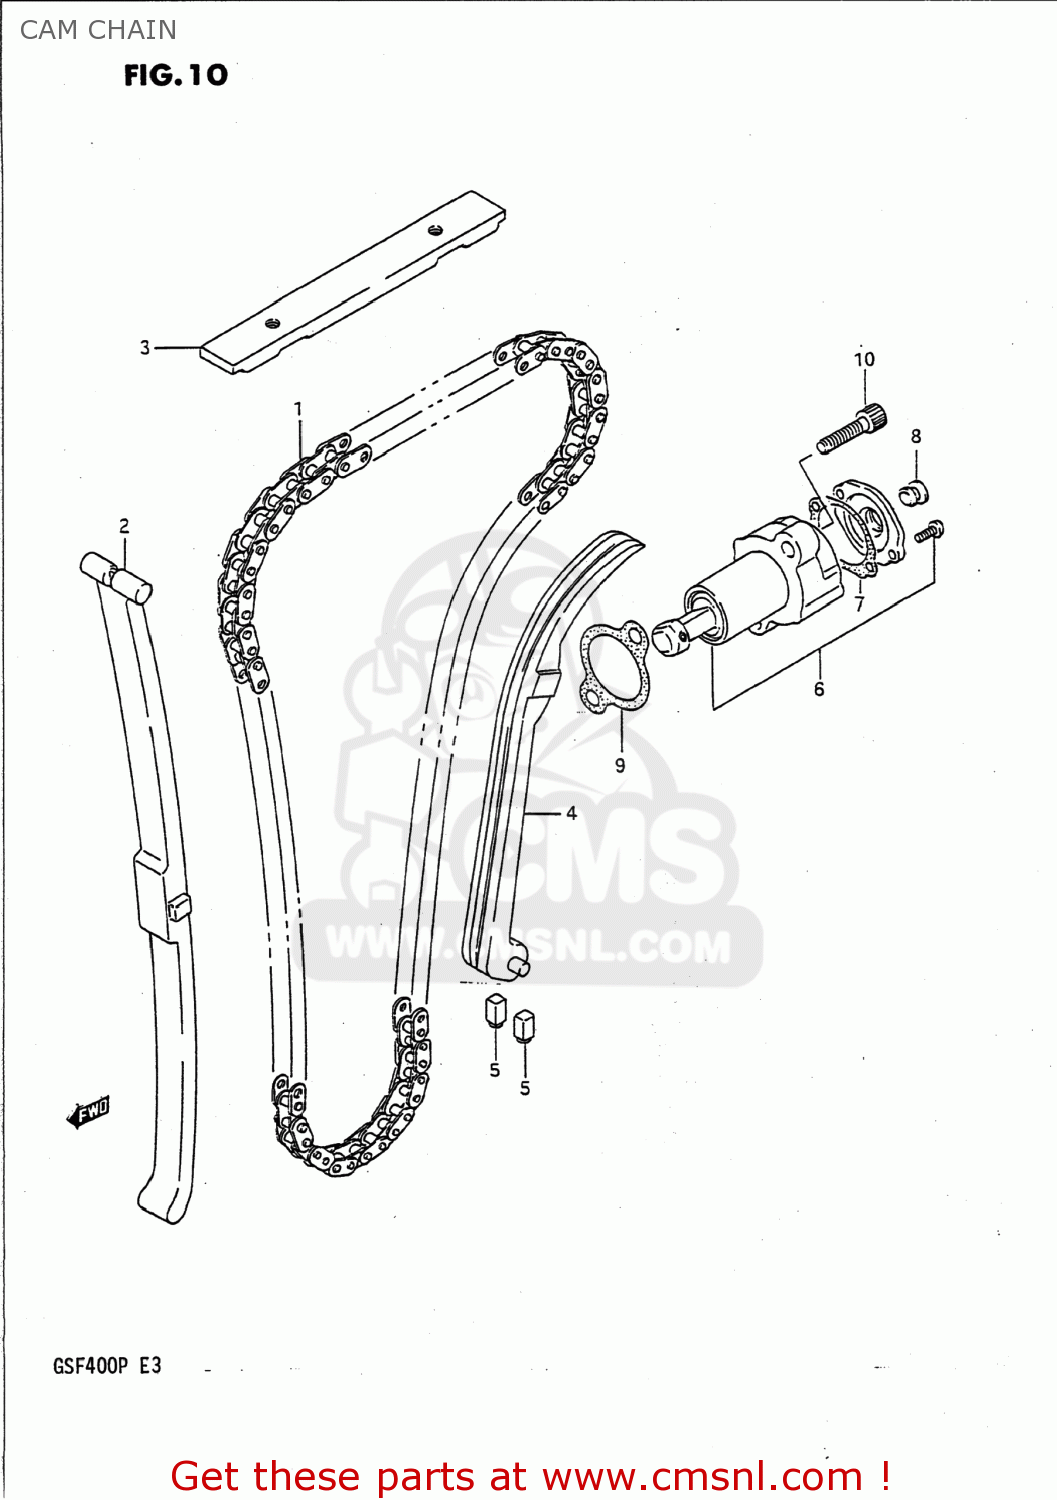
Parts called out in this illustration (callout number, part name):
1	CHAIN,CAMSHAFT DRIVE
2	GUIDE,CAM CHAIN NO.1
3	GUIDE,CAM CHAIN NO.2
4	TENSIONER,CAM CHAIN
5	CUSHION,CAM CHAIN TENSIONER
6	ADJUSTER ASSEMBLY,TENSIONER
7	GASKET,ADJUSTER CAP (NAS)
8	PLUG,ADJUSTER
9	GASKET,TENSIONER ADJUSTER (NAS)
10	BOLT
